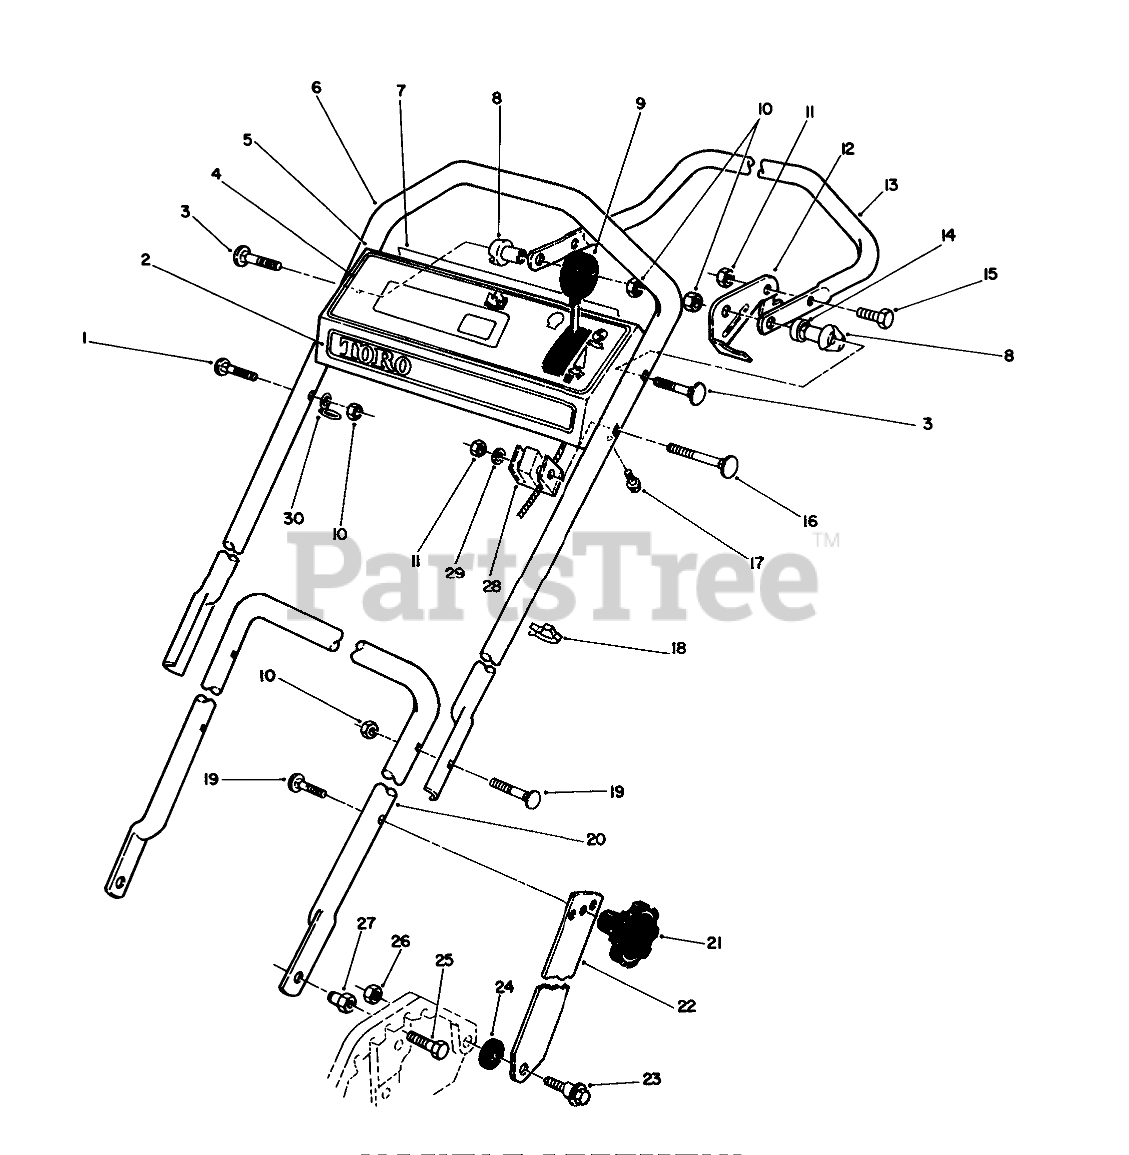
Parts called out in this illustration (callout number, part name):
1	HANDLE SCREW
2	DECAL - TORO, PANEL
3	5/16-18 X 2 HNDLE SCREW
4	DECAL - INSTR. (INT'L)
5	Panel-Control (Incl. Ref. #4)
6	UPPER HANDLE
7	DECAL - PANEL, REAR
8	SPACER-SUPPORT
9	THROTTLE CONT-SERVICE
10	NUT-LOCK, NI
12	LEVER-CONTROL
13	CONTROL BAR
14	SPACER-NYLON
15	SCREW-HH
16	HANDLE SCREW
17	SCREW-HWHTF
18	BOWDEN CLIP
19	SCREW
20	LOWER HANDLE
22	Handle Latch
23	SCREW-SHOULDER
24	SPACER
25	SCREW-HH
26	NUT-LOCK, NI
27	HANDLE PIVOT NUT
28	SUPPORT-CABLE
29	WASHER-FLAT
30	Guide
